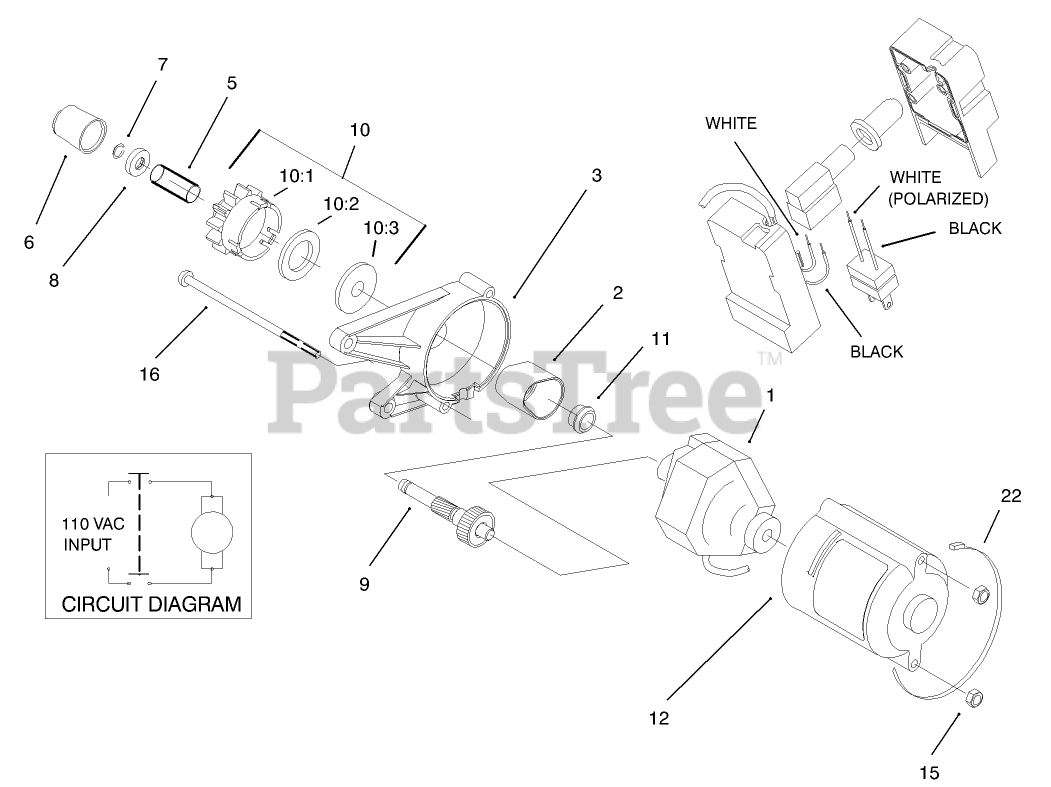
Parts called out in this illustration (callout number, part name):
2	COVER-GEAR
3	HOUSING-UPPER, STARTER
5	SPRING
6	CAP-PINION
7	RING-LOCK
8	STOP-PINION
10	PINION ASM
10:2	PINION
10:3	RING-RUBBER
11	BUSHING
12	HOUSING-LOWER, STARTER
15	NUT-LOCK, NI
22	TIE-CABLE
